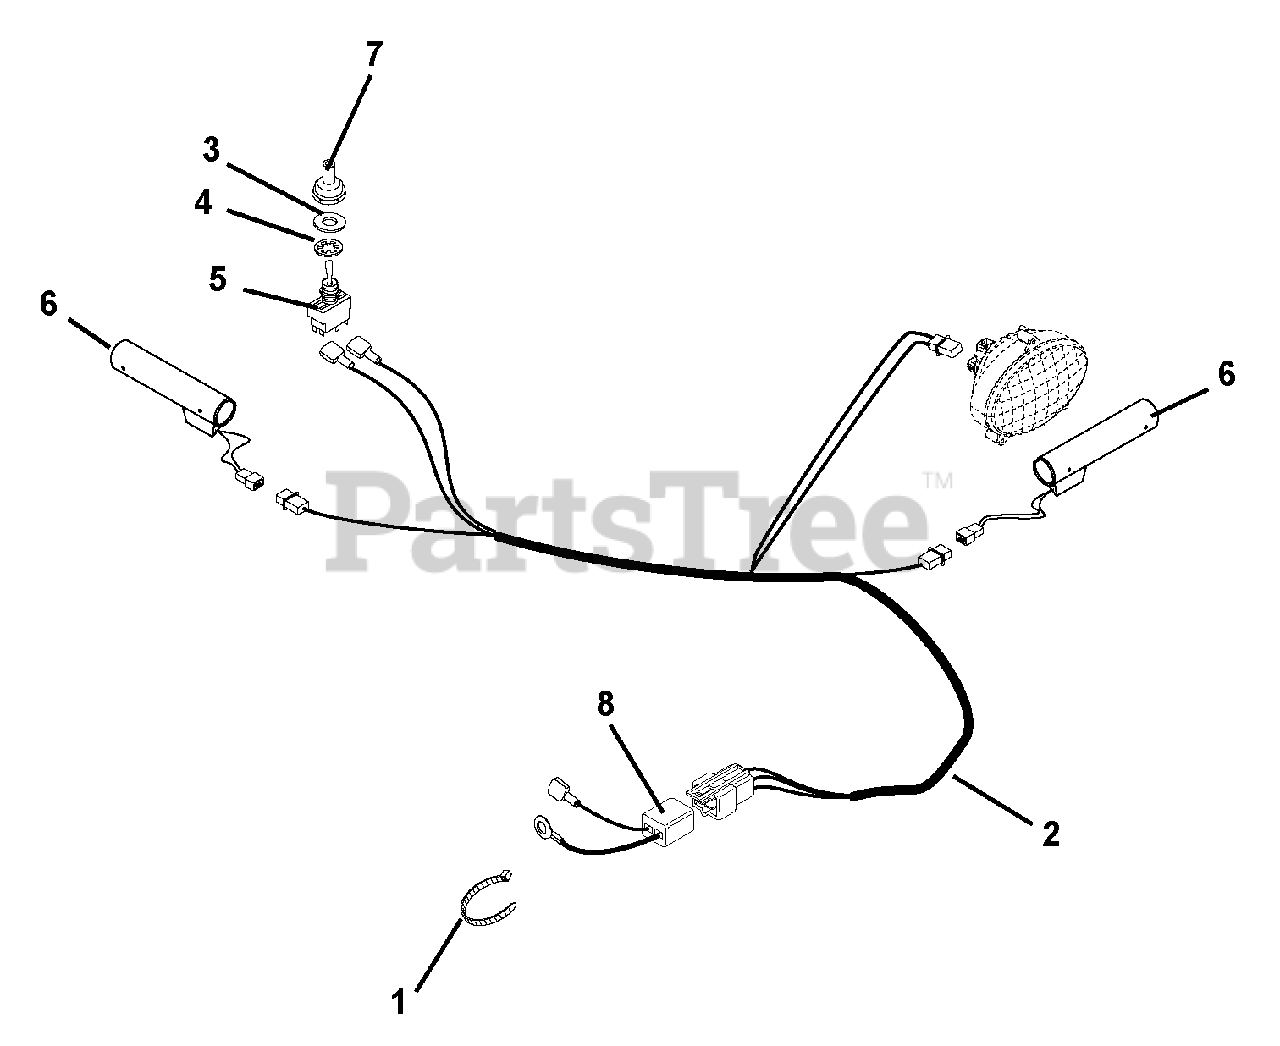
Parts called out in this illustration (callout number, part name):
1	CABLE TIE LG 5-1/2
2	HARNESS, WIRE-LIGHT HANDWARMER
3	WSHR-FL-STL .505X.875X.024 PL
4	WSHR-LK-INT .563X.040 YWZC
5	SWITCH, ON/OFF
6	WARMER, HAND W/TERMINAL
7	BOOT, SWITCH
8	HARNESS ADAPTER, BRIGGS 9A DC
